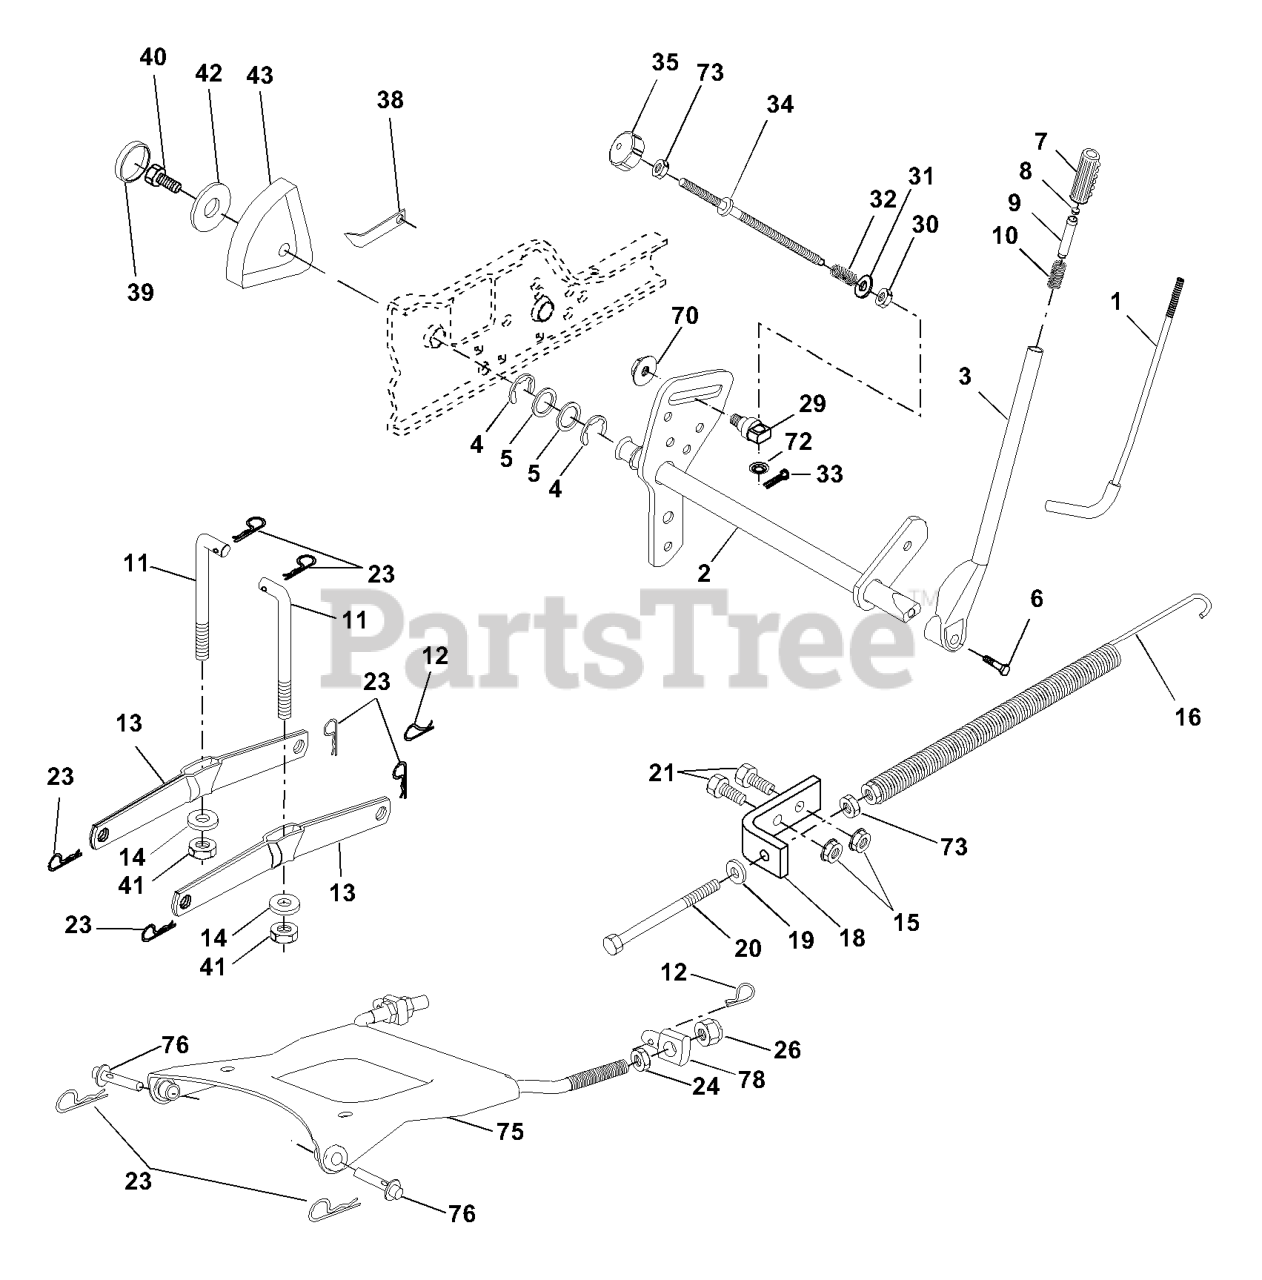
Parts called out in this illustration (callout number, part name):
1	LEVER ROD LT
2	SHAFT ASM, LIFT
3	LEVER ASSY-LIFT RH
5	Washer 29/32 x 1-1/4 x 16 Ga.
6	Bolt, Fin Hex 3/8-16 x 1-1/2
7	GRIP HANDLE
8	PLUNGER BUT KIT
9	PLUNGER BUT KIT
10	SPRING**
11	LINK LIFT
12	SPRING RETAINER
13	ARM.REAR.SUSPENSION
14	BEARING.PIVOT.LIFT
16	LIFT SPRING
19	WASHER
21	BOLT
22	FRONT LINK
23	RETAINER-SPRNG RB
24	NUT.HEX.JAM.1/2-13
26	NUT.LK.W/WSH.1/2.
32	SPRING.COMP.INF.H
33	COTTER PIN
34	ROD.LIFT.ADJUSTABLE
35	KNOB INF 3/8-16
38	POINTER, HEIGHT INDICATOR(2 2)
40	SCREW 5/16-18X1
41	NUT CROWNLOCK 3/8-24
43	HEIGHT INDICATOR
70	NUT
72	NUT PUSH M
73	NUT
75	PLATE ASM SUSP FRONT
76	PIN.FLANGE
